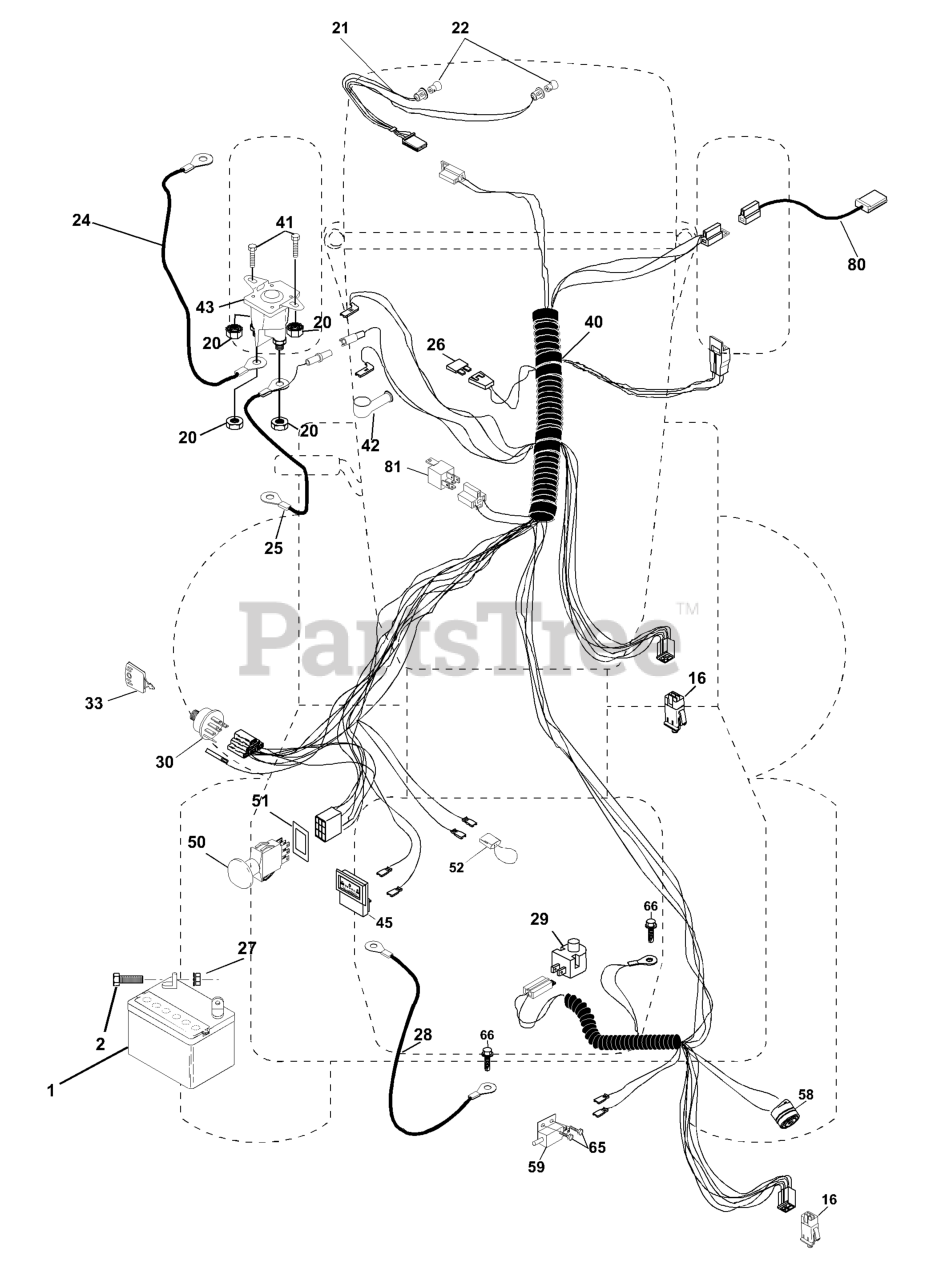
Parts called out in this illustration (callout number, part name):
1	BATTERY 12 VOLT 25 AMP
2	BOLT
16	SWITCH INTERLOCK
24	BATTERY CABLE GT
25	CABLE BATTERY
26	FUSE 15 AMP
27	NUT
28	CABLE GROUND
29	PLUNGER SWITCH (COLOR:OLIVE)
30	SWITCH IGN
33	KEY MLD GEN DELTA
40	HARNESS.ING.CRD.ELECT
41	BOLT
42	TERMINAL COVER
43	SOLINOID
50	PTO SWITCH
51	FRAME RETAINING RING
52	WIRE PROTECTION LOOP
58	BUZZER
65	SCREW
66	SCREW
80	HARNESS, CLUTCH
81	RELAY.ASSY.T
